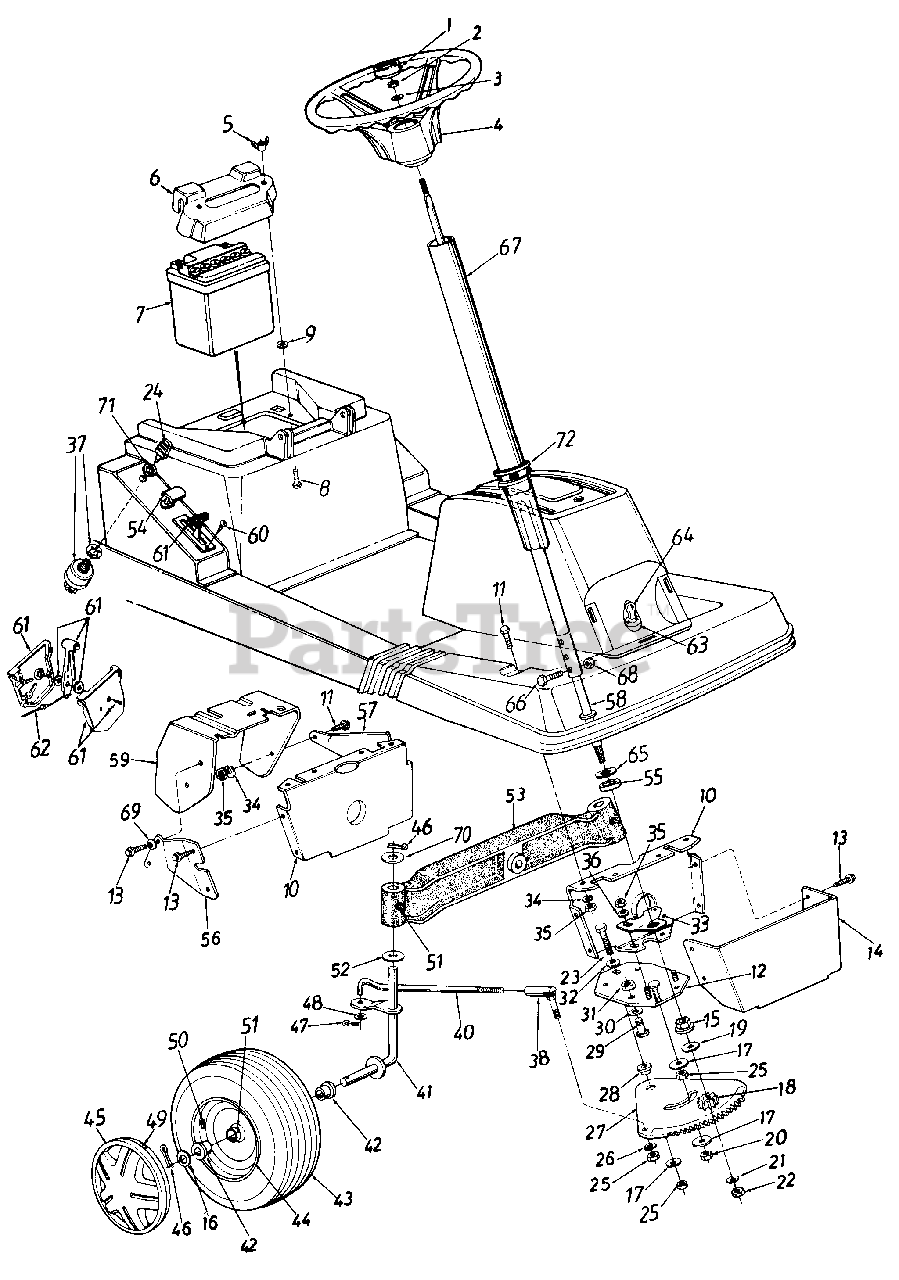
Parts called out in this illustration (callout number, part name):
1	Steering Wheel Cap
2	Hex L-Nut 5/16-24 Thd.
3	Bell-Wash. .345" I.D. x .88" O.D.
4	Steering Wheel Ass'y.
5	Wing Nut 1/4-20 Thd. (Nylon)
6	Battery Hold Down Cover
7	12V Battery
8	Hex Bolt 1/4-20 x 1.75" Lg.
9	Push On Retaining Ring
16	Fl-Wash. .635" I.D. x 1.585"
17	Fl-Wash. .385" x 1.37" O.D.
18	Steering Pinion Gear
19	Fl-Wash. .510" I.D. x 1.0" O.D.
20	Hex L-Nut 3/8-24 Thd.
21	Fl-Wash. .34" I.D. x .68" O.D.
22	Hex Nut 5/16-24 Thd.
23	Hex Bolt 3/8-24 x 1.5" Lg. (Gr. 5)
24	Ignition Key Set
25	Hex Nut 3/8-24 Thd.
26	L-Wash. 3/8" I.D.
27	Steering Gear Segment
28	Shld. Spacer
29	Hex Bolt (Nylon) 1/2-13 x .75" Lg.
30	Fl-Wash. .53" I.D. x .93" O.D.
31	Hex Nut 1/2-13 Thd.
32	Bell-Wash. .385" I.D. x .88"
33	Steering Gear Adjuster
34	L-Wash. 5/16" I.D.
35	Hex Nut 5/16-18 Thd.
36	Spr. Wash. .32" I.D. x .62" O.D.
37	Ignition Switch
38	Ball Joint Ass'y.
40	Steering Tie Rod
41	Front Axle Ass'y.-R.H.
42	Flange Bearing (Bronze)
43	Wheel Ass'y. Comp.
45	Hub Cap
46	Cotter Pin 1/8" Dia. x 1.25" Lg.
47	Cotter Pin 1/8" Dia. x 1.0" Lg.
48	Fl-Wash. .385" I.D. x .87" O.D.
49	Spring Clip
50	Air Valve
51	Grease Fitting
52	Fl-Wash. .76" I.D. x 1.49" O.D.
55	Spacer .985" I.D. x 1.25"
59	Clutch Pedal Brkt. Ass'y.
60	Truss Mach. AB-Tap Scr. #10 x .5" Lg.
61	Throttle Control Box Ass'y.
62	Throttle Control Wire 26" Lg.
63	Headlight Socket
64	Lamp
65	Fl-Wash. .64" I.D. x 1.24"
66	Hex Bolt 1/4-20 x 1.25" Lg.
67	Steering Shaft Ass'y.
68	Hex L-Nut 1/4-20 Thd.
69	Bell-Wash. .345" I.D. x .88" O.D.
70	Fl-Wash. .75" I.D. x 1.5" O.D.
71	Ignition Switch Nut
72	Steering Cover Brg.
